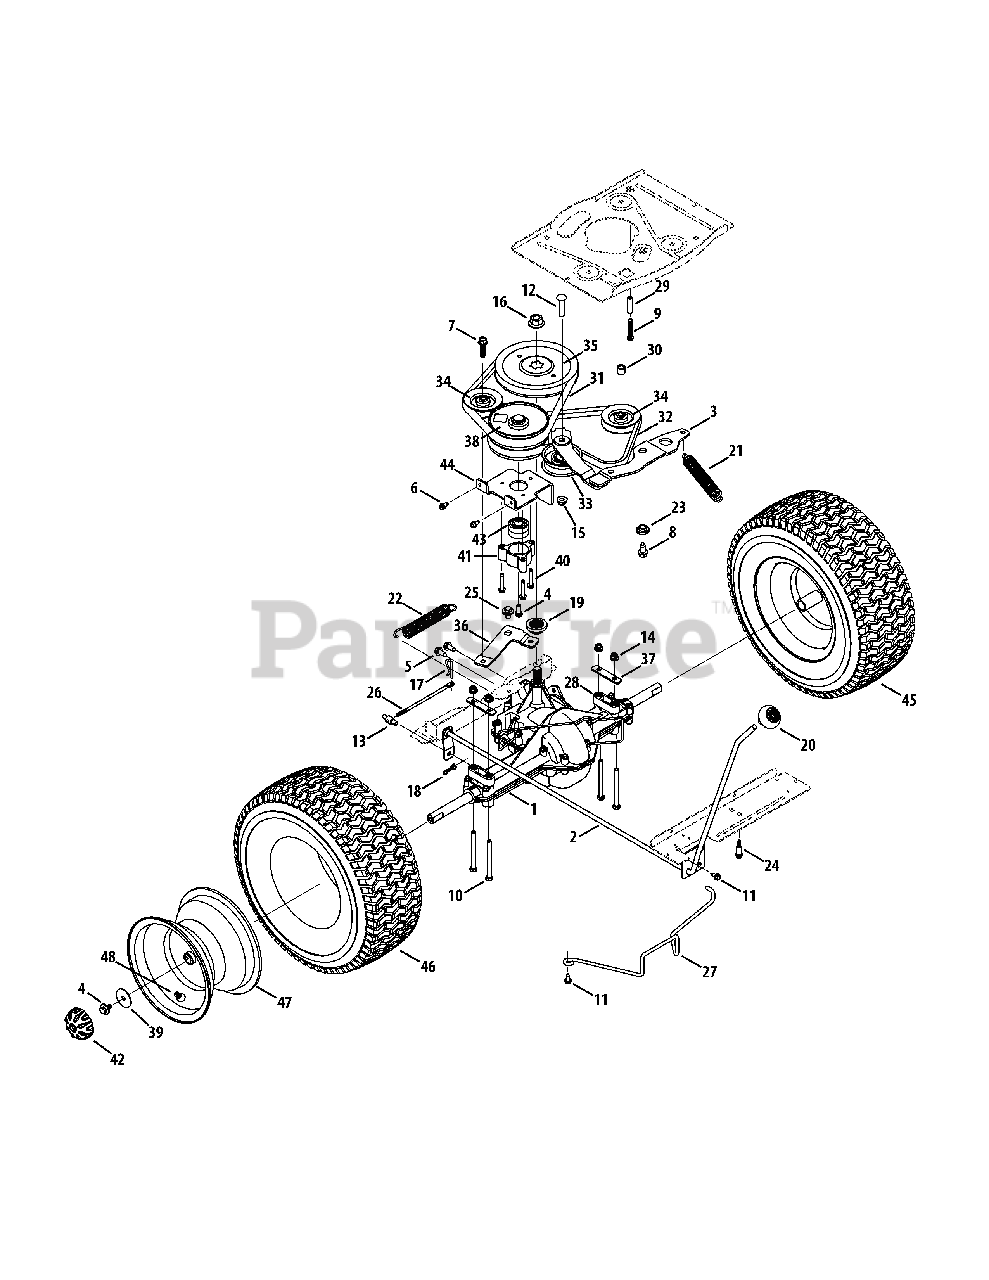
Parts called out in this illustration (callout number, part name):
1	Transmission Assembly
2	Shift Handle Assembly
3	Drive Assembly Idler
4	Screw, 5/16-24 x .750
5	Tap Screw, 5/16-18, .750
6	Tap Scew, 1/4-20, 0.500
7	Screw, 3/8-16 x 1.375
8	Tap Screw, 3/8-16, 0.750
9	Screw, 1/4-20 x 1.750
10	Hex Cap Screw, 5/16-18 x 3.5, Gr5
11	Tap Screw, 1/4-20 x .625
12	Screw, Carriage: 3/8-16 x 1.69"
13	Adjustable Ferrule, 1/4-20 X 1.00
14	Flange Locknut, 5/16-18
15	Flange Lock Nut, 3/8-16
16	Flange Nut, 9/16-18
17	Internal Cotter Pin, .125 Dia.
18	Bow-Tie Cotter Pin
19	Pulley Hub, 5/8 Spline
20	Shift Knob
21	Extension Spring, .94 Dia. X 6.74 Lg.
22	Extension Spring, .97 OD X 6.18
23	Shoulder Spacer, 1.00 X .38 X .38
24	Shoulder Screw, .368 x .75, 1/4-20
25	Shoulder Screw, .560 x .165, 5/16-18
27	Deck Belt Keeper, 30"
29	Spacer, .260 X .372 X 1.420
30	Spacer, .385 x .625 x .500
31	V-Belt, 5L:35.25
32	V-Belt, 5L:35.28
33	Flat Idler Pulley, 2.75 OD
34	V-Type Idler Pulley, 3.06
35	V-Type Pulley, 6.56
36	Rear Idler Arm Bracket
37	Transaxle Mounting Bracket
38	Variable Speed Pulley Assembly
39	Flat Washer, .35 x 1.59 x .062
40	Tap Screw, 1/4-20:1.500
41	Bearing Cup
42	Hub Cap
43	Ball Bearing, 17 X 40 X 12
44	Variable Bracket
45	Complete Wheel Assembly
46	Tire, 16 x 6.5 x 8 Sq. Shldr.
47	Rim Assembly, 8.0 x 5.38
48	Air Valve
